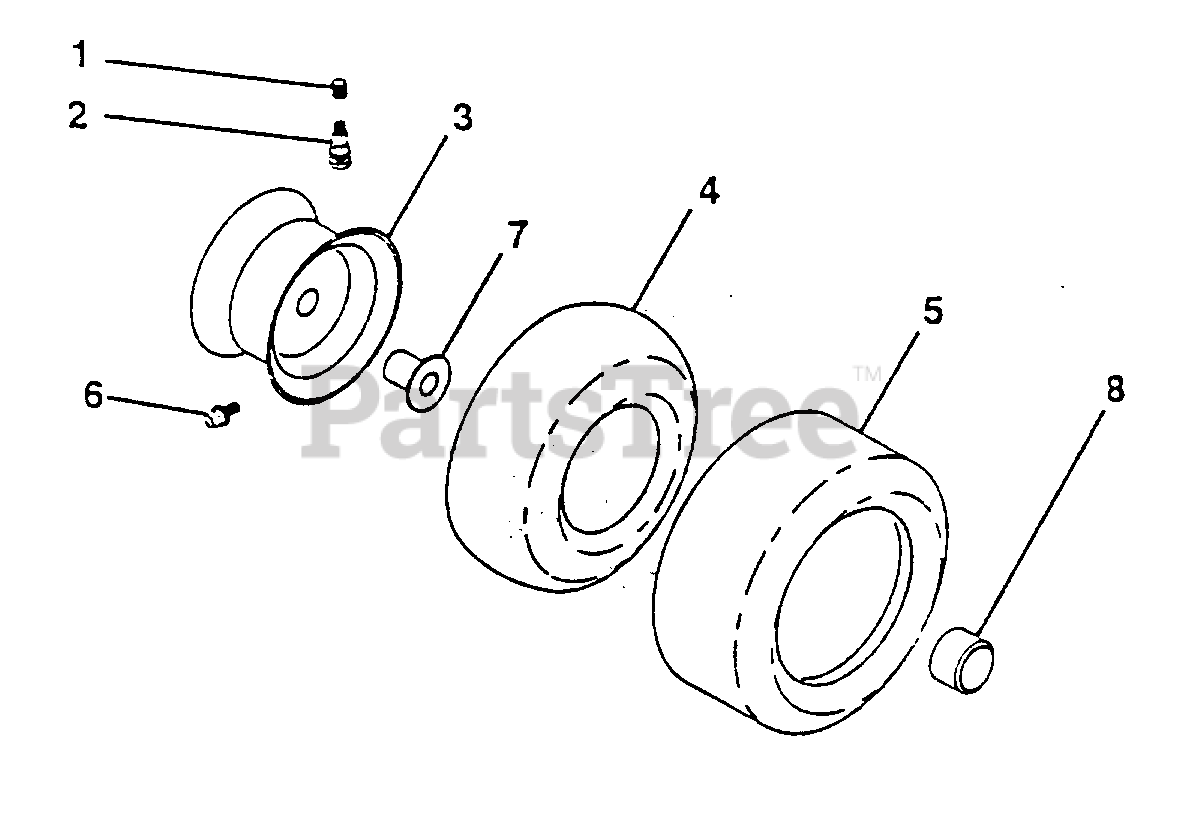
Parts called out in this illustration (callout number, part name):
1	Cap, Valve, Tire (AYP part number)
2	Stem, Valve (AYP part number)
3	Rim Assembly, Front (AYP part number)
4	Tube, Front (Service Item Only) (AYP part number)
5	Tire, Front (AYP part number)
6	Fitting, Grease (AYP part number)
7	Bearing, Flange (Front Wheel Only) (AYP part number)
8	Cap, Hub (AYP part number)
9	Tube, Rear (Service Item Only) (AYP part number)
10	Tire, Rear (AYP part number)
11	Fitting, Grease (AYP part number)
